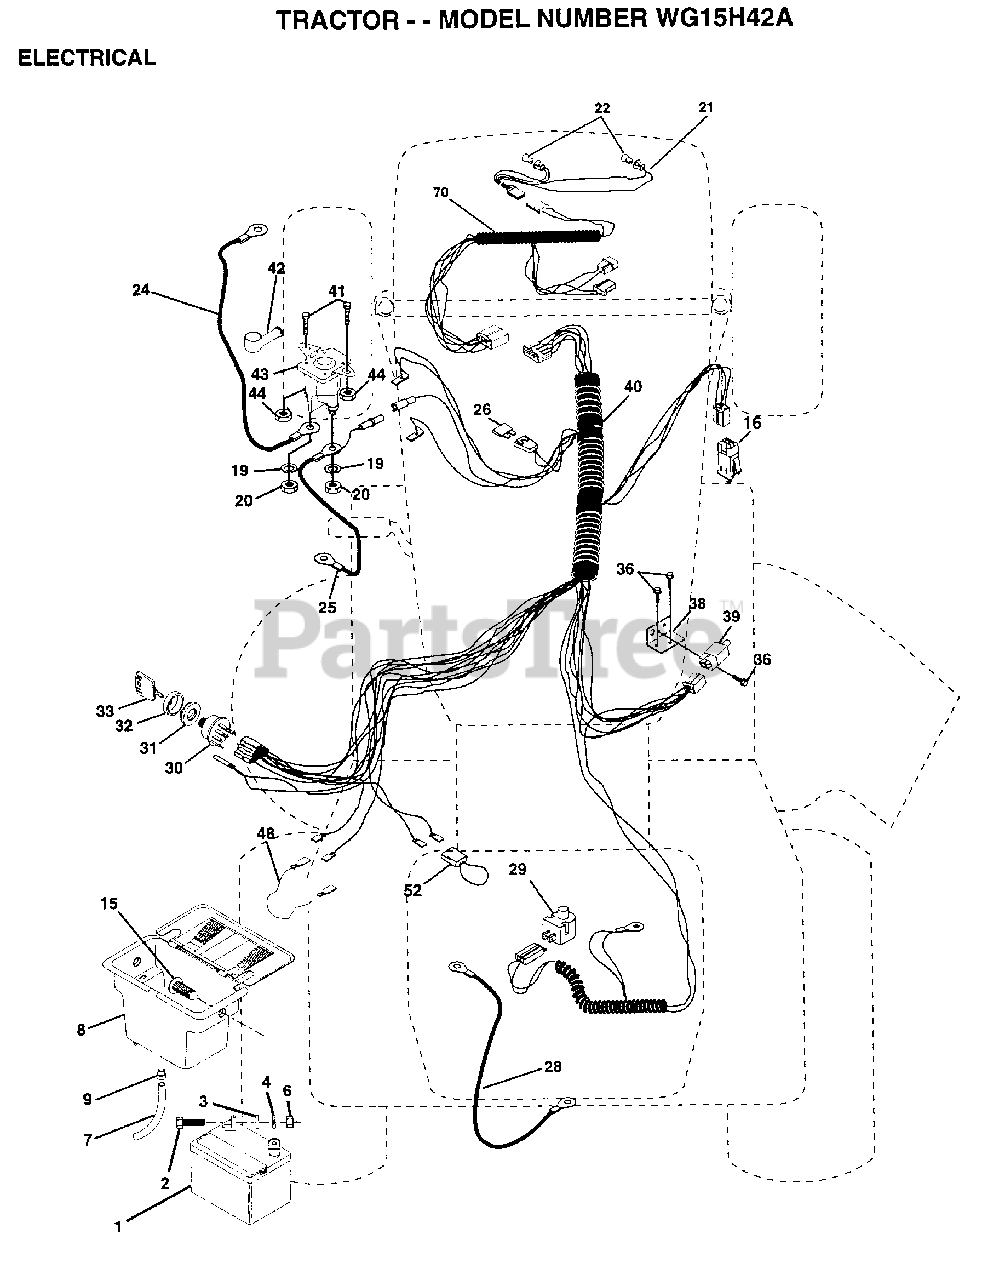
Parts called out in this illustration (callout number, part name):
2	BOLT LT
3	WASHER
4	LOCKWASHER
7	TUBE T
9	HOSE CLAMP T
15	FASTNER.SNAP-IN
16	SWITCH INTERLOCK
20	NUT
21	"HARNESS,LIGHT SOC"
22	HEADLAMP BULB
24	"CABLE T, BATTERY"
25	CABLE.BTRY.6GA.RD
26	SCREW
28	CABLE T
29	SWITCH SEAT
30	SWITCH IGN 4POS
31	NUT IGNITION
32	COVER KEY SWITCH
33	KEY
36	SCREW
38	BRACKET SWITCH IN
39	SWITCH INTERLOCKT
40	HARNESS.IGNITION
41	BOLT HXHD FIN
44	NUT HXKEP 1/4X20
48	ADAPTER AMMETER
52	PROTECTION LOOP
70	HARNESS ENGINE
